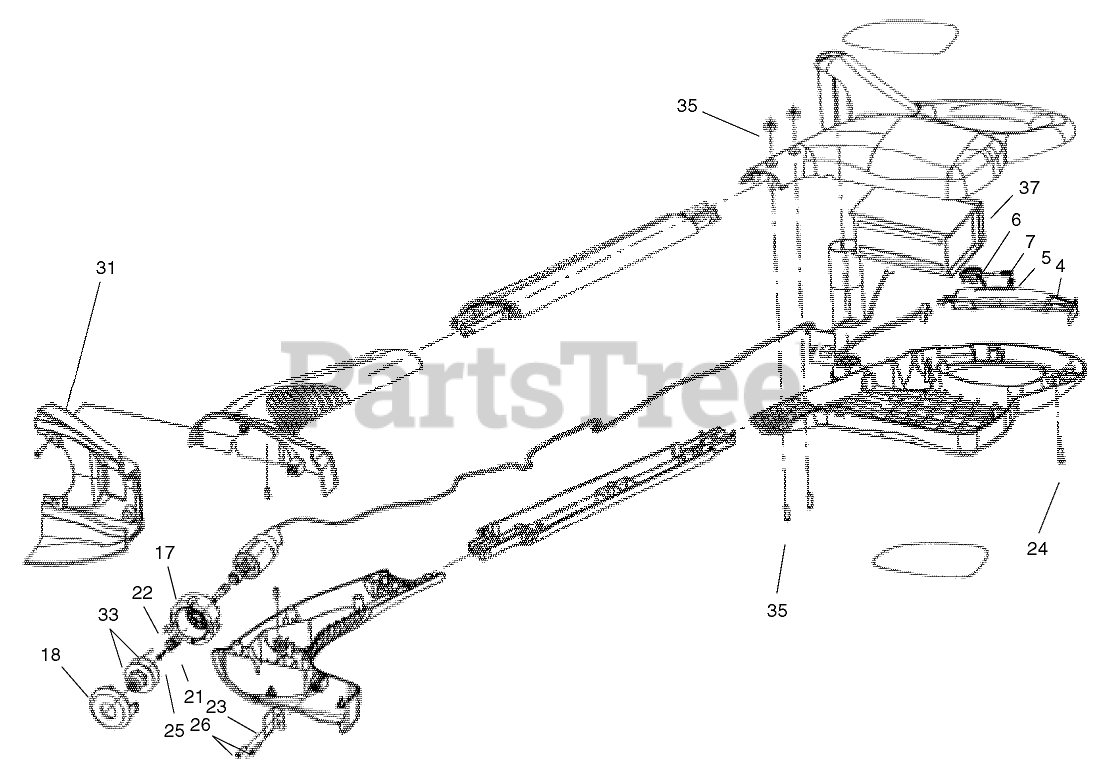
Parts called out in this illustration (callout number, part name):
4	Trigger
5	Spring-Trigger, 7in
6	Lock-Trigger
7	Spring-Switch, 7in
17	Drum-Trimmer, 7in
18	CAP-SPOOL, 7 INCH
21	SPRING-COMPRESSION
22	EYELET
23	Cutter
24	Screw-Plastic Thd Form
25	Screw-Machine
26	Screw-Plastic Thd Form (only on: 51460)
26	Screw-Plastic Thd Form (only on: 51461)
31	Shield-7in Trimmer (Ce)(only on: 51461)
33	SPOOL ASM
35	ASM-Bolt Bag
37	7IN BATTERY ASM
